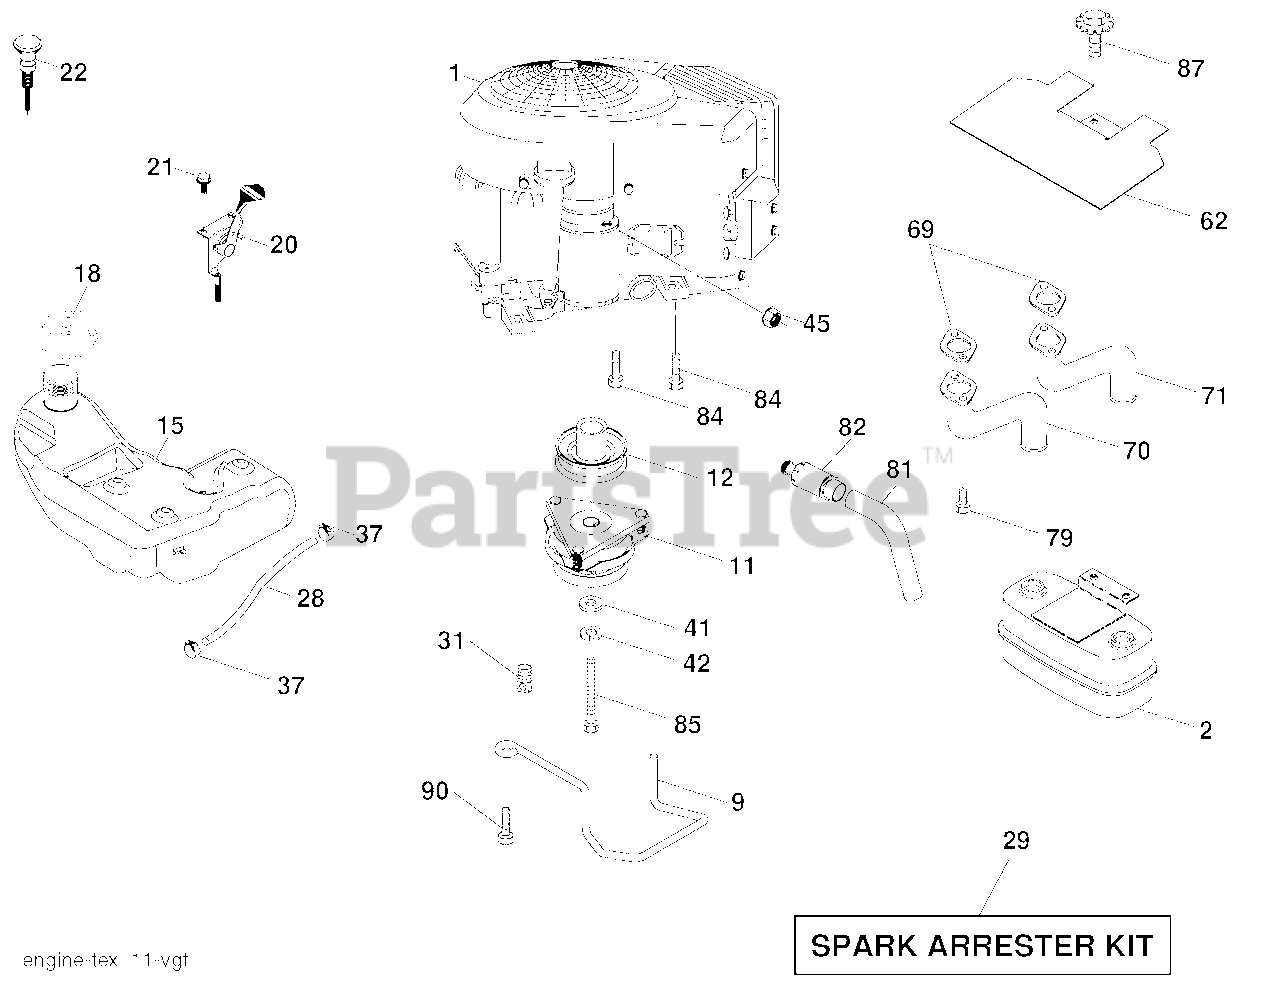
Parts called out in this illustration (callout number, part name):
2	Muffler
9	Keeper Belt Engine
11	Clutch Electric
12	Pulley Engine
15	Tank Fuel 3.0
18	Cap Asm
20	Control Throttle
21	Screw 10 x 3/4 Single Lead-Hex
22	Control Choke
28	Fuel Line
29	Spark Arrester Kit
31	Clip Push-In Hinged
37	Clamp Hose
41	Washer 1-1/2 OD x 15/32 ID x .250
42	Washer Lock 7/16
45	Nut Keps Hex 1/4-20 unc
62	Shield Heat Muffler
69	Gasket
70	Exhaust Tube RH
71	Exhaust Tube LH
79	Screw Socket Head 5/16-18 x 1
81	Tube Drain Oil Easy
82	Plug Drain Oil
84	Screw 3/8-16 x 1-1/4
85	Bolt Hex 7/16-20 x 4 x 1/4 5 Ga.
87	Bolt 5/16-18 x 3/4
90	Screw 3/8-16 x 1
